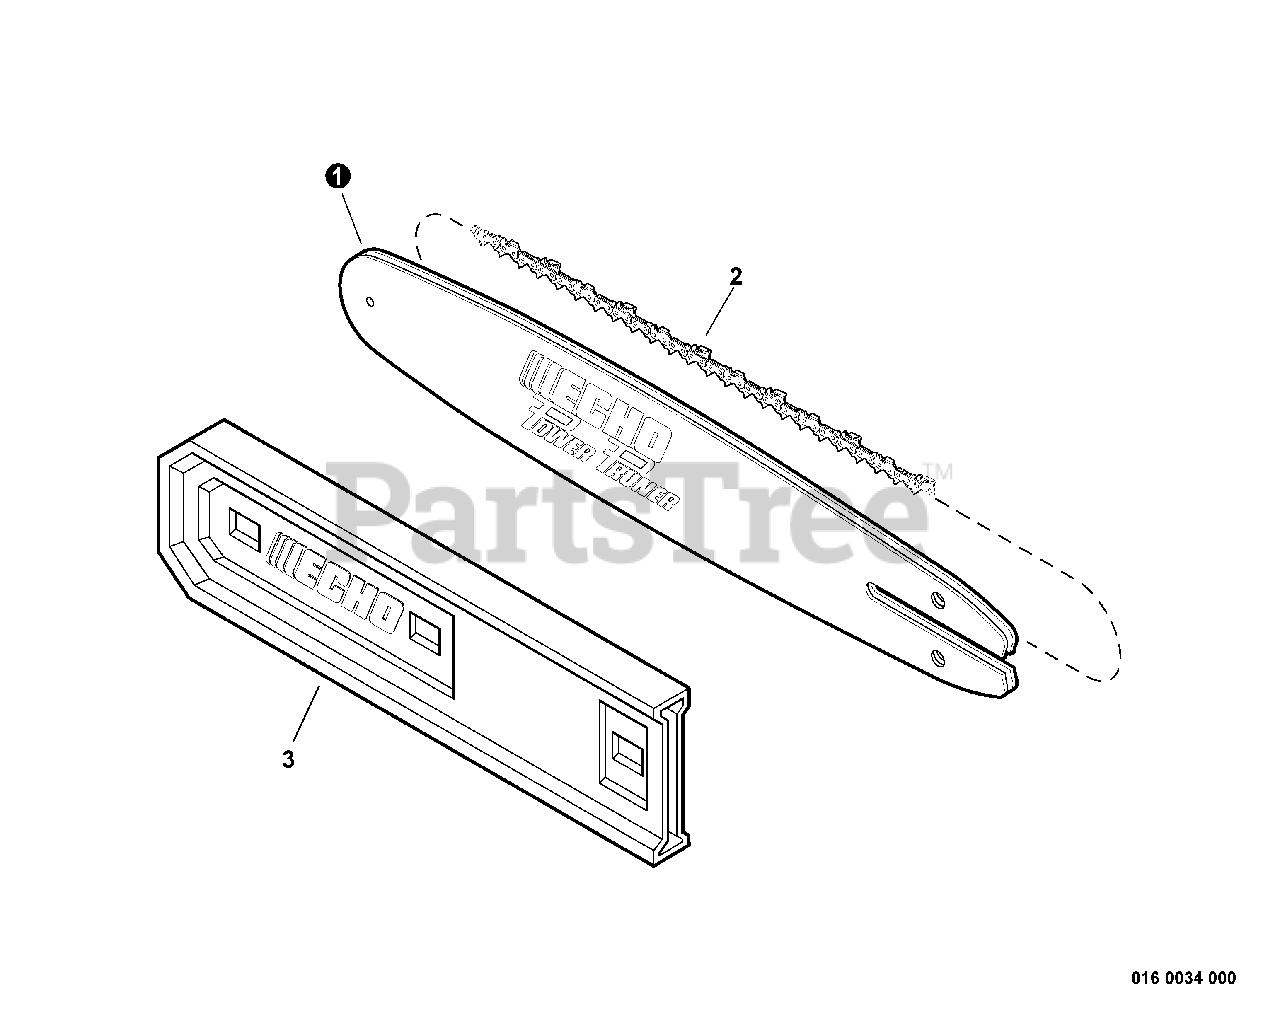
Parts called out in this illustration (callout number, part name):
1	GUIDE BAR - 12" (30cm) Intenz
2	SAW CHAIN - 12" (30cm)
3	COVER, GUIDE BAR - 12" (30cm)
